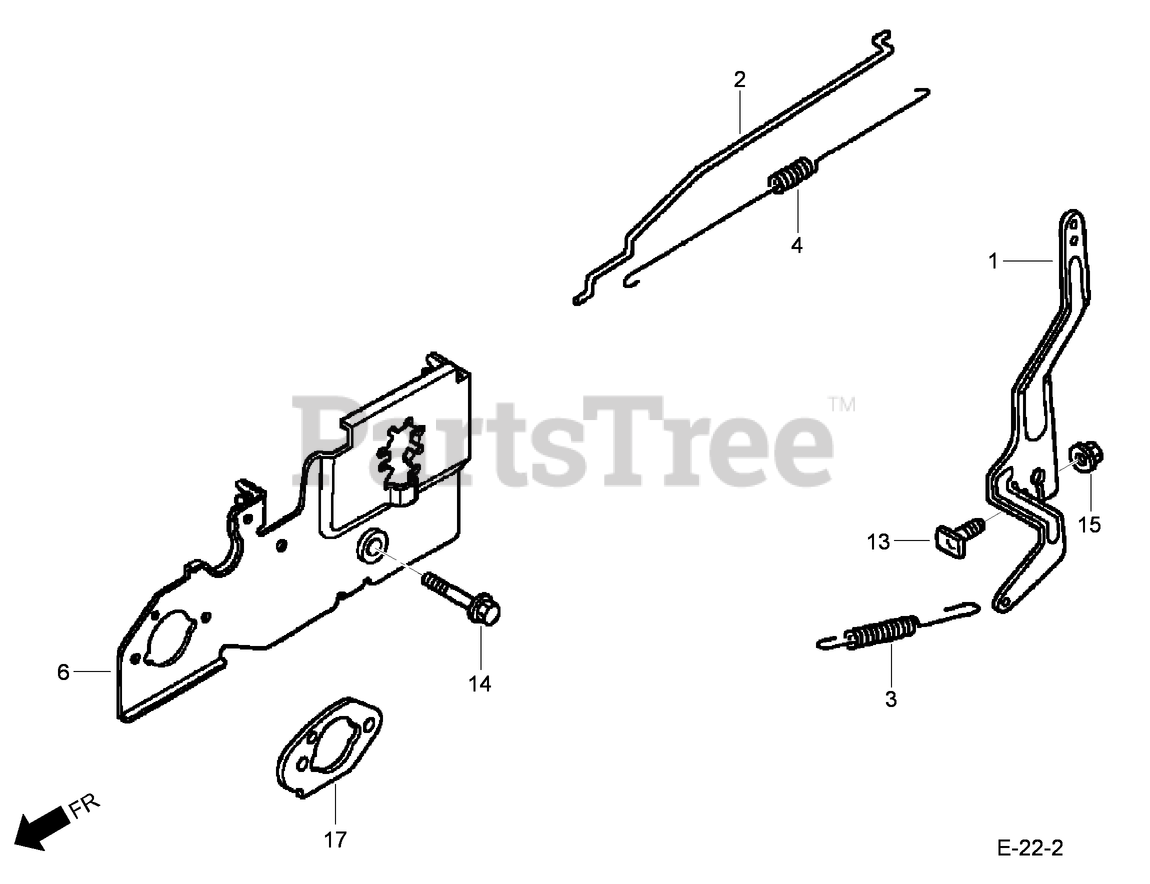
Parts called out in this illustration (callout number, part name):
1	ARM-GOVERNOR
2	ROD-GOVERNOR (engine serial numbers up to 6349022)
2	ROD-GOVERNOR (engine serial numbers starting at 6349023)
3	SPRING-GOVERNOR
4	SPRING-RETURN, THROTTLE
6	BASE-CONTROL (engine serial numbers up to 6901760)
13	BOLT-ARM, GOVERNOR
14	BOLT-FLANGE (6X45) (C T200)
15	NUT-FLANGE (6 mm)
17	SPACER-CARBURETOR (engine serial numbers starting at 6901761)
